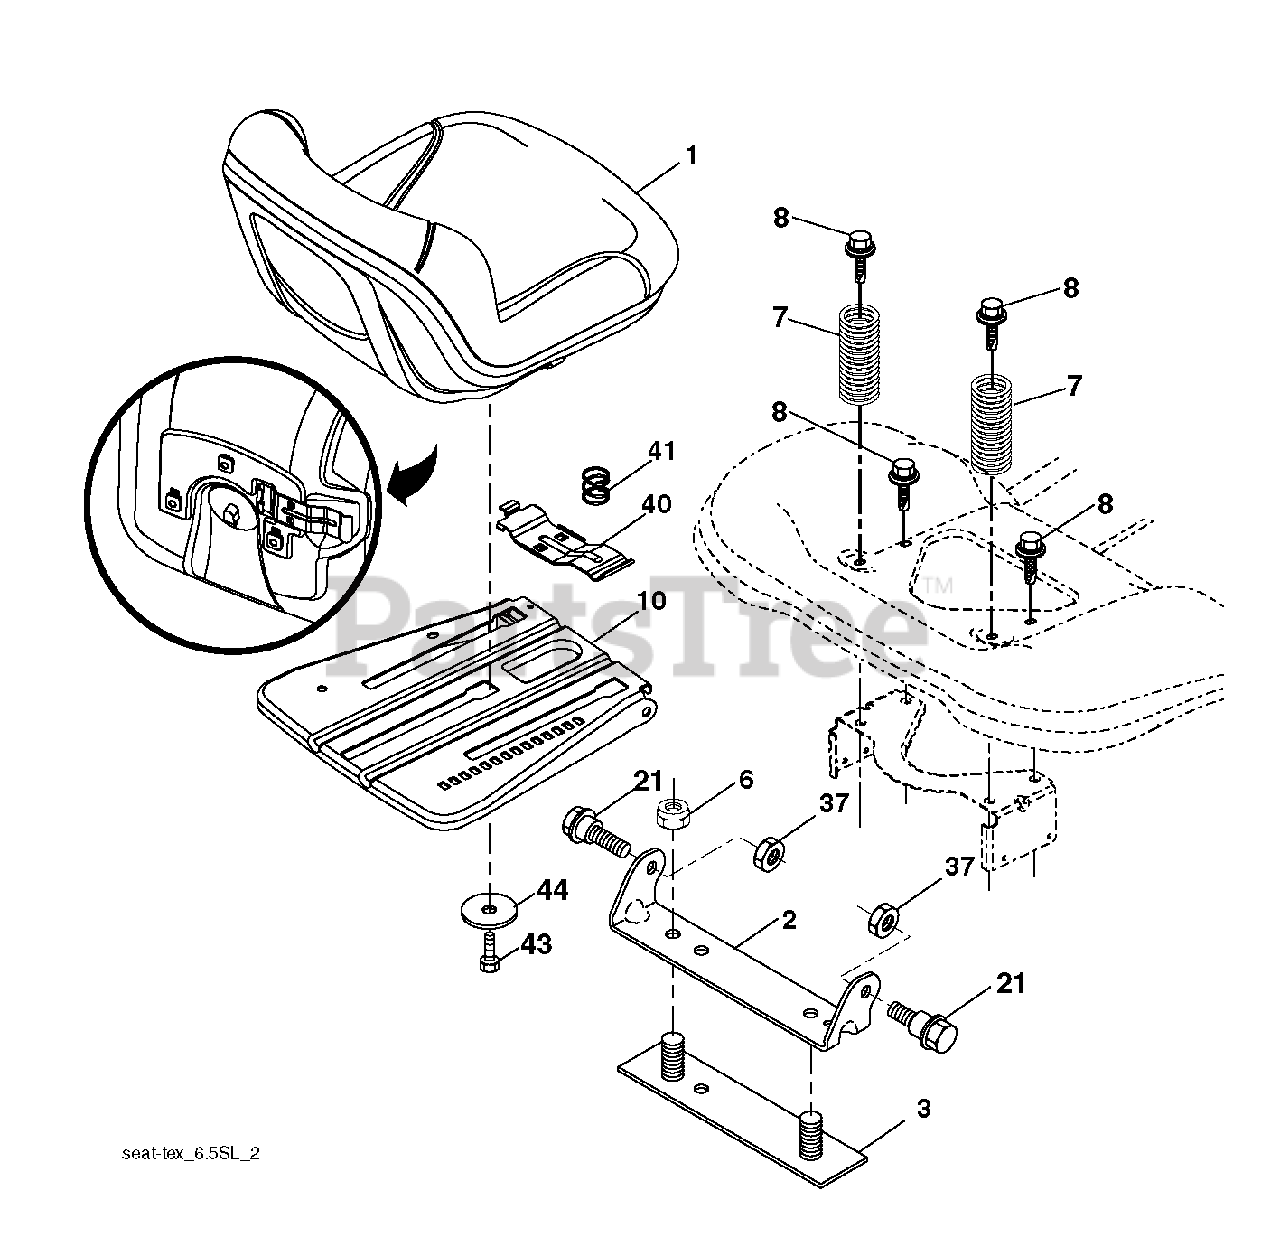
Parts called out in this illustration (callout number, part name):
2	BRKT.PIVOT.FENDER
3	STRAP
8	BOLT, 5/16-18 X 1 3/4
10	PAN.ASM.SEAT.3PT
21	BOLT, SHOULDER
40	HANDLE.SLIDE.SEAT.TEX.
41	SPRING.LATCH.SEAT.TEX
44	WASHER 13/32 X 2-3/8 X 12GA
